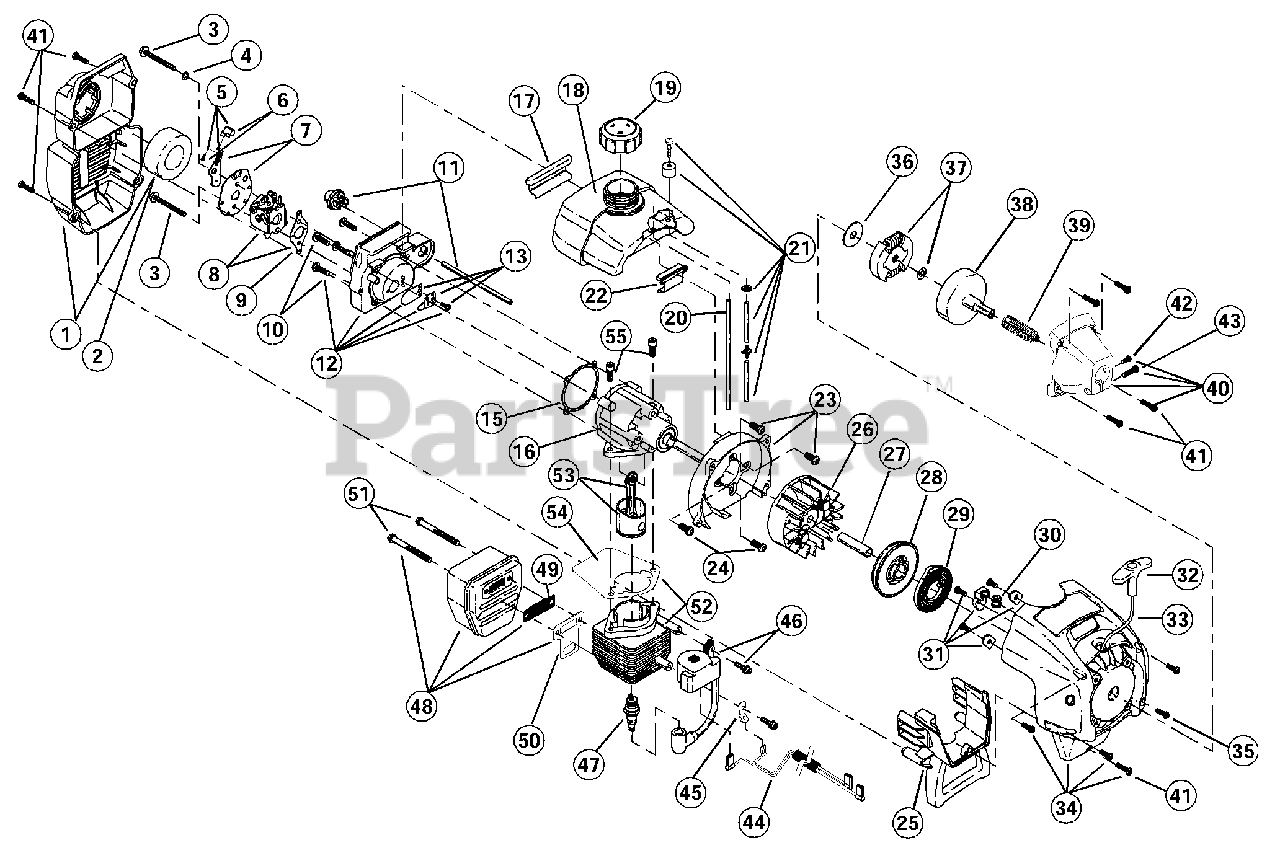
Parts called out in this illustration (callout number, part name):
1	Air Cleaner/Muffler Cover Assembly (includes 2 & 41)
2	Air Cleaner Filter
3	Carburetor Mounting Screw Assembly
4	Wavey Washer
5	Choke Lever Assembly (includes 6)
6	Choke Knob and Screw
7	Choke Lever and Plate (includes 5)
8	Carburetor Assembly W/Limiter Caps (includes 9 & 21)
9	Carburetor Gasket
10	Carb Mount Screw
11	Primer and Hose Assembly
12	Carb Mount Assembly (includes 10)
13	Reed Assembly
15	Carburetor Mount Gasket
16	Crank Case Service Assembly (includes 10, 14 & 24)
17	Rear Mounting Pad
18	Fuel Tank Assembly (includes 19-21)
19	Fuel Cap Assembly
20	Fuel Return Line
21	Fuel Line Assembly
22	Front Mounting Pad
23	Shroud Assembly
24	Shroud Screw
25	Shroud Extension and Stand
26	Flywheel Assembly
28	Recoil Pulley Assembly
29	Recoil Spring
30	Rope Guide
31	Pulley Retainer Assembly
32	Pull Handle
34	Starter Housing Assembly (includes 28-33 & 41)
35	Housing Screw
36	Clutch Washer
37	Clutch Rotor Assembly
38	Clutch Drum Assembly
40	Clutch Cover Assembly (includes 41-43)
41	Cover Screw
42	Anti-Rotation Screw
43	Clamping Screw
44	Wire Leads and Sleeve
45	Ground Tab
46	Module Assembly
47	Spark Plug
48	Muffler Assembly (includes 49-51)
49	Spark Arrestor Screen
50	Exhaust Gasket
51	Muffler Mounting Bolt Assembly
52	Cylinder Assembly (includes 54)
53	Piston and Rod Assembly
54	Cylinder Gasket
55	Cylinder Bolt
